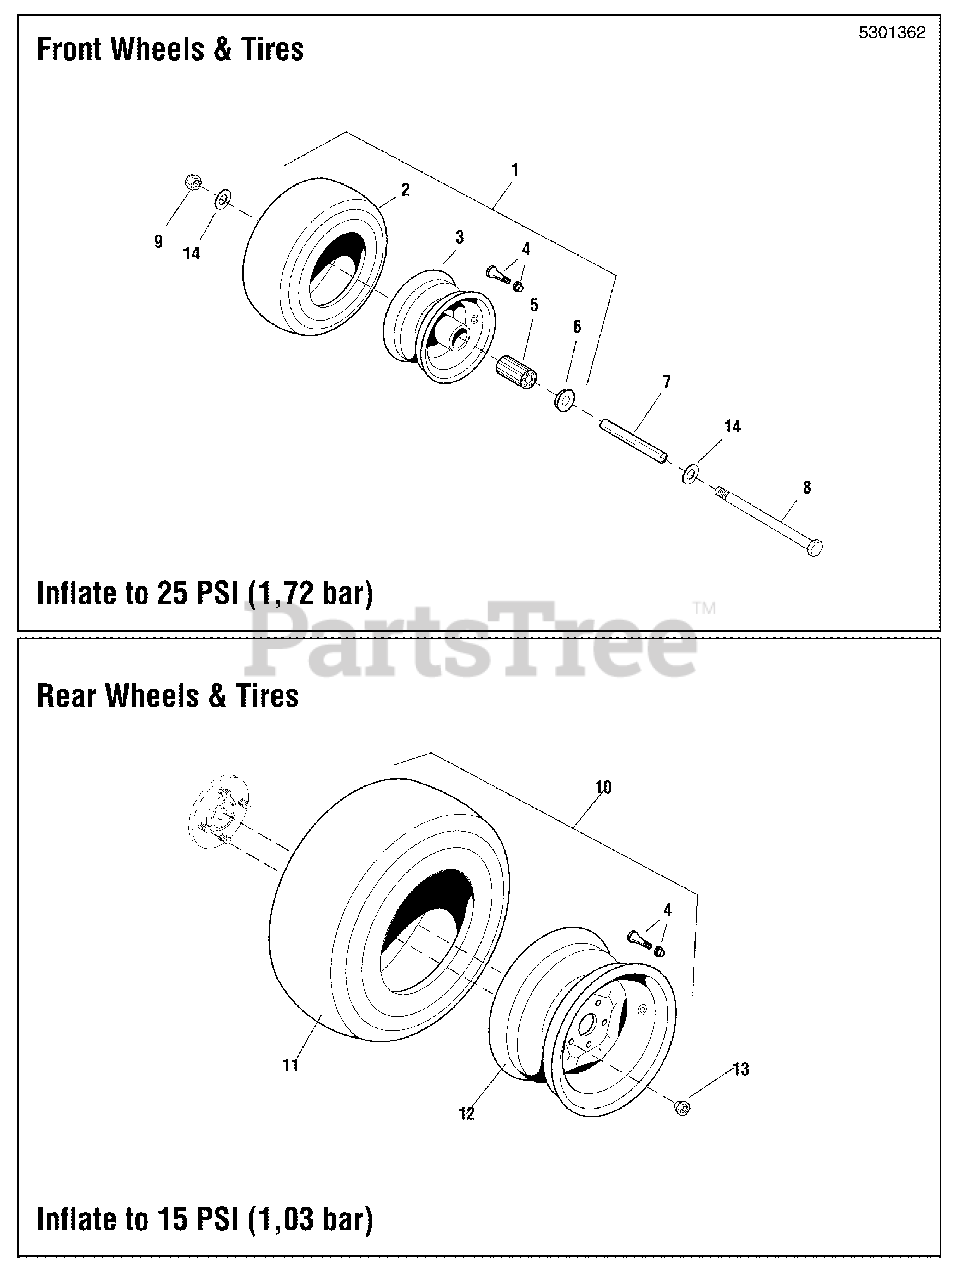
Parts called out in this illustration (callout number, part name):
1	WHEEL, CASTER, 11 X 4.0-5 SILVER BEAD LO
2	TIRE, Front, 11 X 4.0 - 5 (SV)
3	WHEEL ASSEMBLY, 11 X 4.0 - 5 TIRE CMP (SV)
4	VALVE STEM & CAP ASSEMBLY (SV)
5	BEARING, CASTER WHEEL, 11 X 4.0 - 5 BEAD LOCK (SV)
6	BEARING, Retainer
7	CASTER AXLE DDSH
8	BOLT, 1/2-13 X 6-1/2 GD8 YZ
9	NUT, 1/2-13 HEX NYLON LOCK
10	WHEEL+TIRE ASMY REAR 20/8.00-10
11	TIRE, Rear 20 X 8.0 X 10 (SV)
12	WHEEL ASSEMBLY, For 20 X 8.0 X 10 Tire (SV)
13	NUT, 1/2-20, FOR WHEEL BOLT SILVER
14	WASHER, 1/2 SAE
